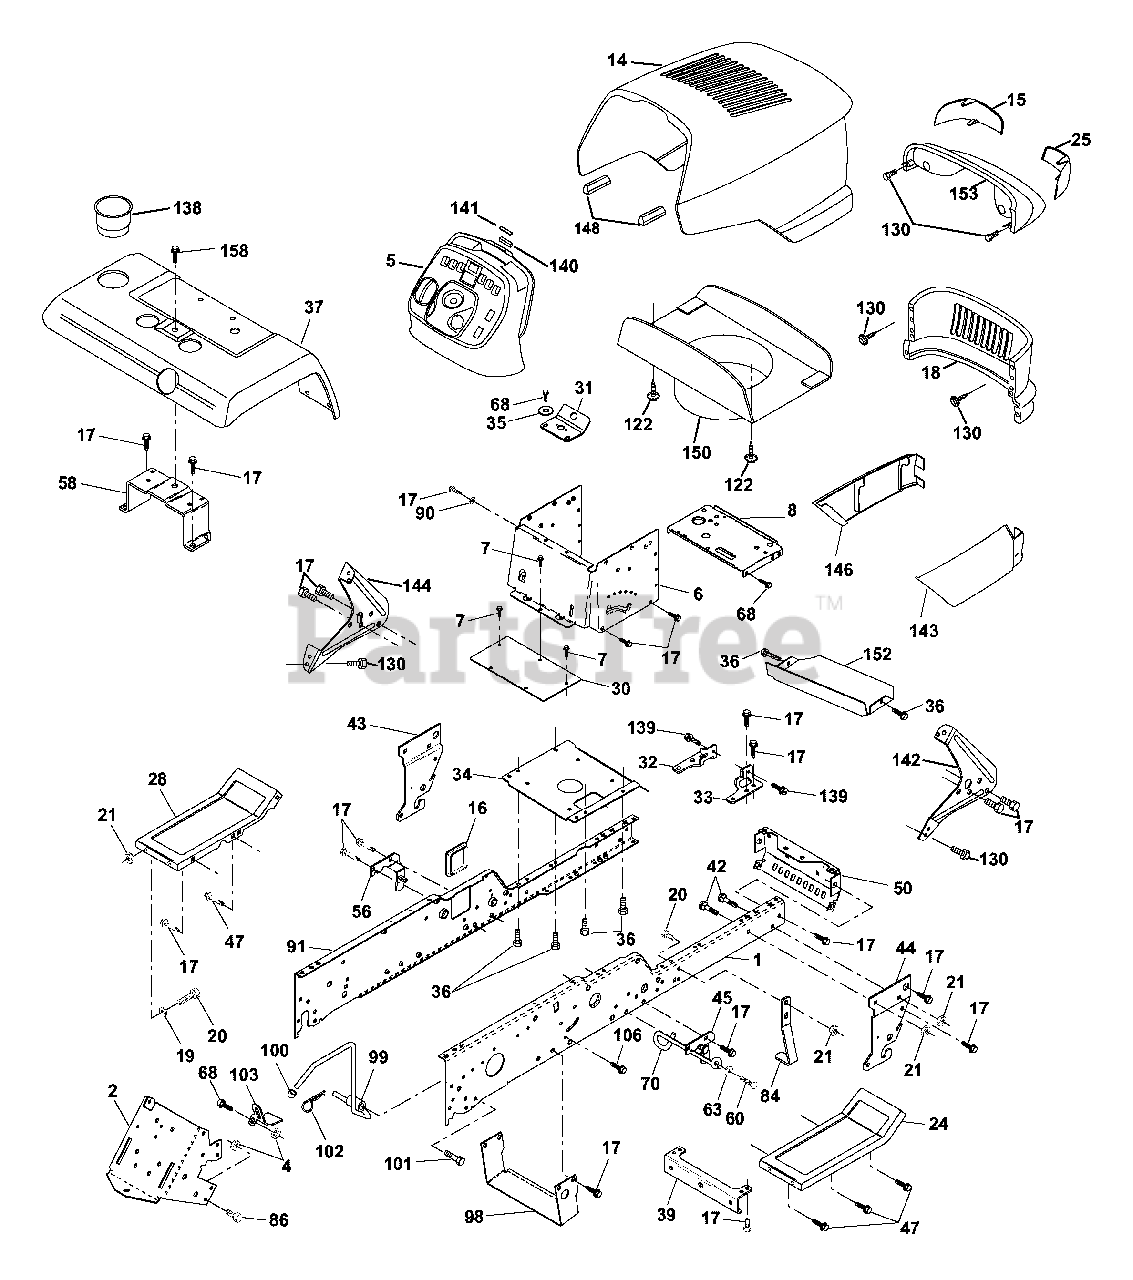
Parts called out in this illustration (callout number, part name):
1	Rail, Frame RH
2	Drawbar, Gt
4	Nut, Lock Hex 7/16 Unc
5	Dash, Plastic
6	Dash, 1PCS, Lower
7	Screw, Thd Cut 1/4-20 x 1/2
8	Support, Battery
14	Hood Asm., Pnt
15	Lens LH
16	Cover, Access
17	Screw, 3/8-16 x 3/4
18	Grille
19	Washer 13/32 x 13/16 x 12 Ga.
20	Bolt, Fin Hex 3/8-16 x 1
21	Nut, Crownlock 3/8-16
24	Footrest, RH
25	Lens RH
28	Footrest, LH
31	Bracket Supt 1-pc Vgt Steering
32	Bracket, Frame Pivot Lh
33	Bracket, Frame Pivot Rh
34	Plate Asm Engine Chassis
35	Washer 11/32 x 11/16 x 16 Ga.
36	Screw 5/16-18 x 3/4
37	Fender, Pnt.
39	Bracket, Axle Front
42	Bolt Rdhd Sqnk 3/8-16 Unc x 1
43	Bracket, Spnsn Front Lh
44	Bracket, Spnsn Front Rh
45	Bracket Asm., Susp Chassis Rh
47	Screw Thdrol 3/8-16 x 1/2
50	Bracket, Chassis Front
56	Bracket Asm., Susp Chassis Lh
58	Bracket Asm., Fender
60	Screw 3/8-16 x 1-1/4
63	Washer 13/32 x 1 x 14 Ga.
68	Screw, 5/16-18 x 1/2
70	Belt Keeper VGT Ground
84	Stop, Over Center Mower
86	Bolt, Fin Hex 7/16-14 Unc x 1
90	Washer, Lock External Tooth 3/8
91	Rail, Frame Lh
98	Bracket Chassis Skid
99	Rod Asm. Bypass
100	Cap By Pass Rod
101	Screw Thdrol. 3/8-16 x 1-3/4
102	Retainer Spring 1"
103	Bracket Lock Bypass
106	Screw Thdrol Hex Head Zinc
122	Screw Hex WSHD 8-18 x 7/8
130	Screw Hw Hd Hi-Lo #13-16 x 3/4
138	Cupholder
139	Bolt Shoulder 5/16-18
140	Magnet Stealth
141	Striker Plate
142	Bracket Dash Stealth RH
143	Skirt Grille RH
144	Bracket Dash Stealth LH
146	Skirt Grille LH
147	Fastener Pal
148	Extrusion Bumper
150	Duct Heat Hood
152	Browning Shield
153	Lens Asm Headlht Dual
158	Screw Thdrol 3/8-16 x 1/2
